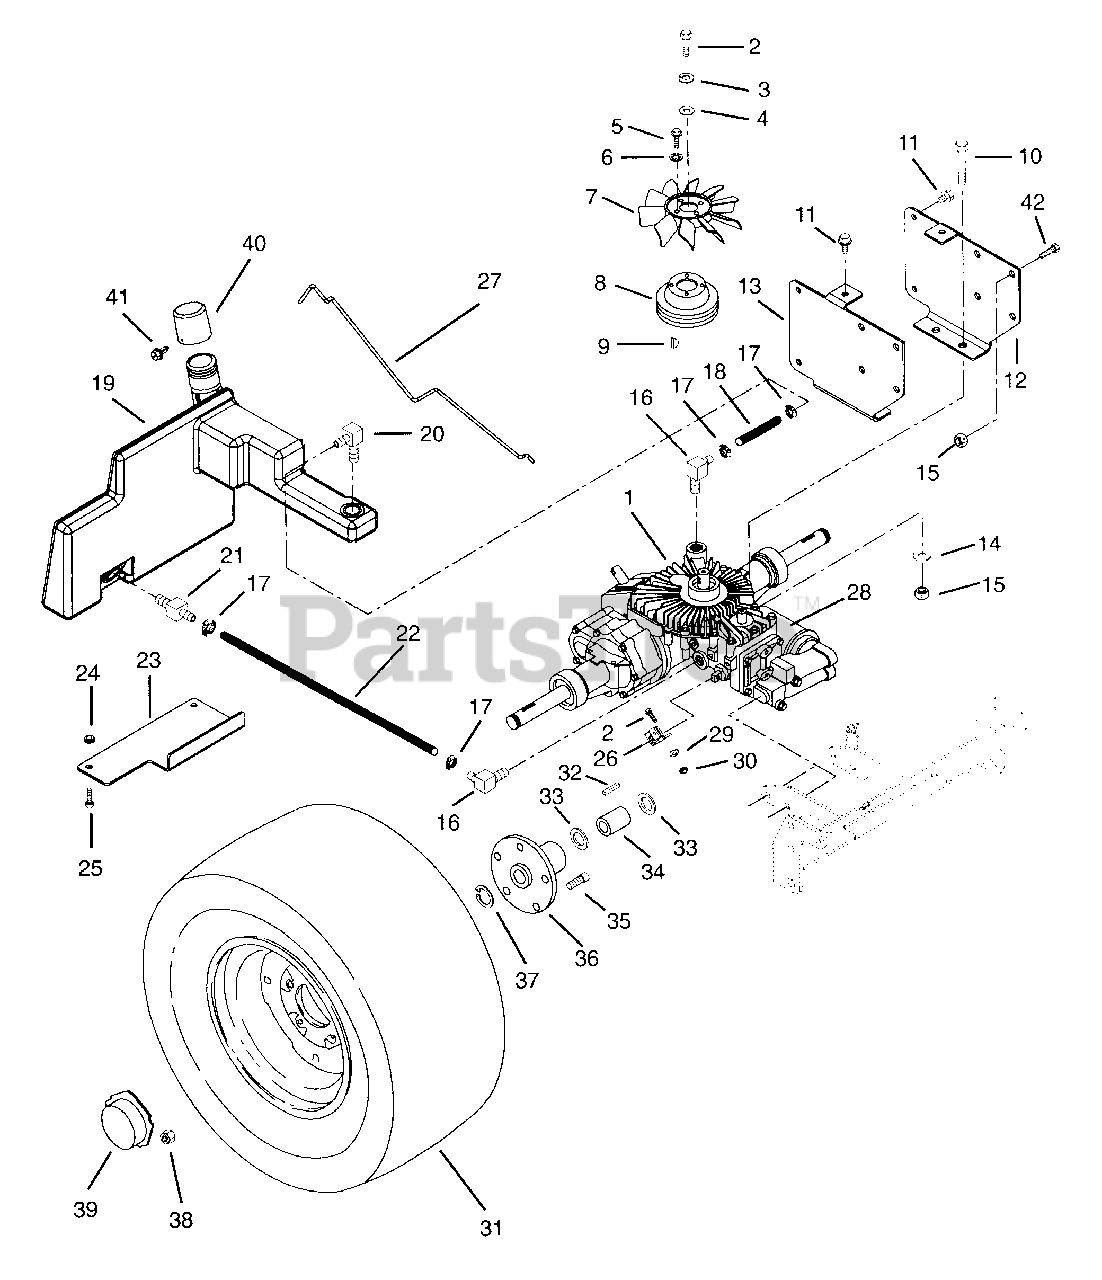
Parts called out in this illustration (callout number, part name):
1	TRANSAXLE - HYDRO
2	@BLT-HEX .25-20X1.00 GR5 YWZC
3	WSHR-LK .250X.077 HVY YWZC
4	WSHR-FL-STL .265X1.370X.179
5	@SCR-MCH 10-24X.50 HWH YWZC
6	@WSHR-LK-EXT.200X.402X.022YWZC
8	SHEAVE - TRANSAXLE
9	KEY-WDRF .188X.625X.25 SAE 61
10	@BLT-HEX .38-16X3.00 GR5 YWZC
11	@SCR-TAP .38-16X.50 HWH TR YWZ
12	MOUNT, AXLE L.H.
13	MOUNT, AXLE R.H.
14	@WSHR-FL-STL.406X.812X.065 YWZ
15	@NUT-LK-CTR .38-16 YWZC
16	FITTING
17	CLAMP-HOSE WRM .38/.62X.50 #10
18	HOSE, .625 ID X.906 OD X 6.50
19	RESERVOIR, OIL
20	ELBOW, BARBED .625
21	ADPTR-MALE
22	HOSE, .625 ID X.906 OD X 10.75
23	BRACE, OIL RESERVOIR
24	@NUT-LK-CTR .31-18 YWZC
25	@BLT-HEX .31-18X.75 GR5 YWZC
26	ARM, DUMP VALVE
27	ROD, DUMP VALVE
28	FILTER, OIL (WISEAL)
29	WSHR-LK .250X.077 HVY YWZC
30	@NUT-HEX .25-20 YWZC
31	T/WHL ASSY 10.50X23
32	KEY-STR .25X2.0X.25
33	WSHR-FL-STL 1.010X1.505X.062YZ
34	SPACER 1.006X1.437X1.928
35	BLT-LUG SERNKHDND .44-20X1.188
36	WHEEL HUB
37	RG-RTNG-EXT 1.00X.078
38	NUT-LUG .437-20 YWZC
39	REAR HUB CAP
40	CAP - OIL RESERVOIR
41	SCR-DR 8-18X.50
42	@BLT-HEX .38-16X.75 GR5 YWZC
